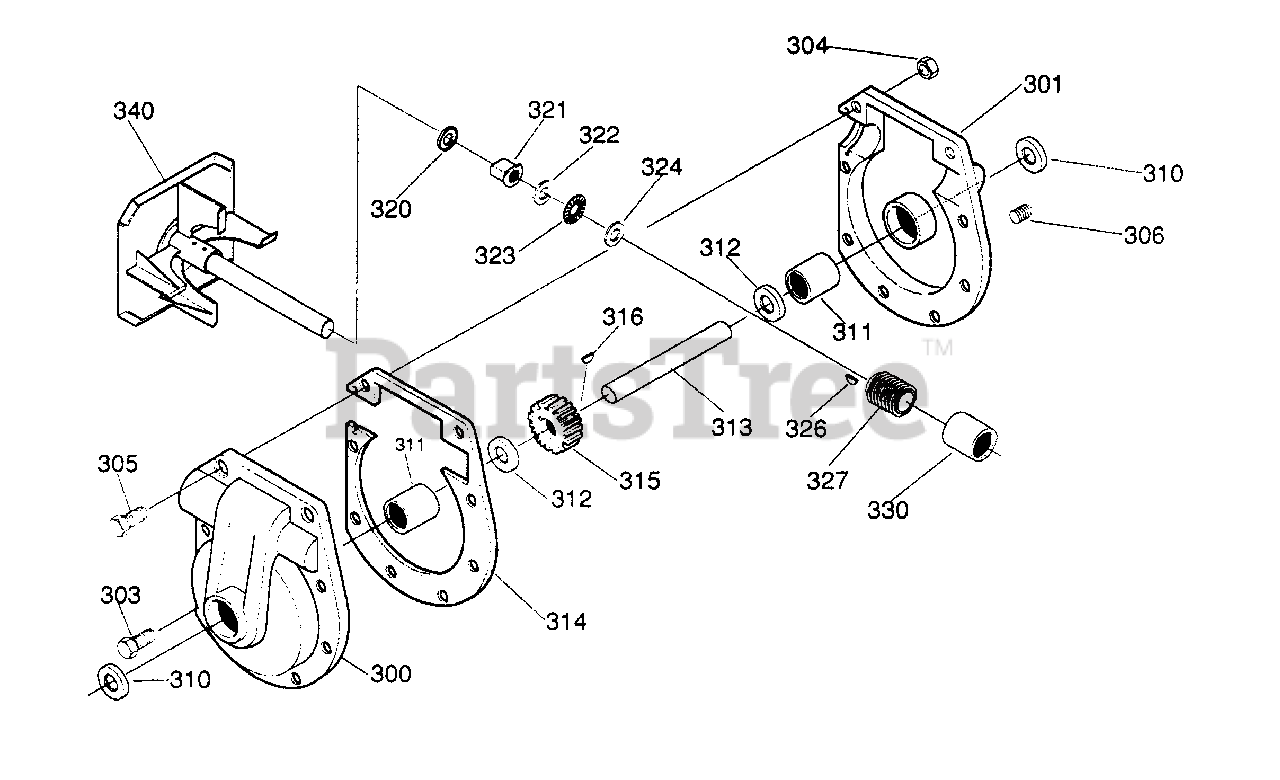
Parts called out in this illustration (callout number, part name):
300	CASE, GEAR, RH
301	CASE, GEAR, LH
303	SCREW, 5/16-240.00 HHC
304	NUT, 5/16-24 HEXWDFLLK
305	SCREW, 5/16-240.50 HHC
310	SEAL, OIL CR 530552 #53744
311	BEARING, SLEEVE
312	FLATWASHER
313	SHAFT, AUGER OUTPUT MF 22"
314	GASKET, GEAR BOX
316	KEY, WDRF #91 .75 DIAx.25 WD
320	RING, QUAD
321	BEARING, FL .753 IDx1.128 ODx1.03
322	FLATWASHER,.752x1.24x.093 PL
323	BEARING, ROLL
324	FLATWASHER,.752x1.24x.093 PL
326	KEY, HI-PRO 606 .75DIAx.187WD
330	BEARING, SLEEVE.752 IDx.88 ODx.755
340	IMPELLER ASSEMBLY
